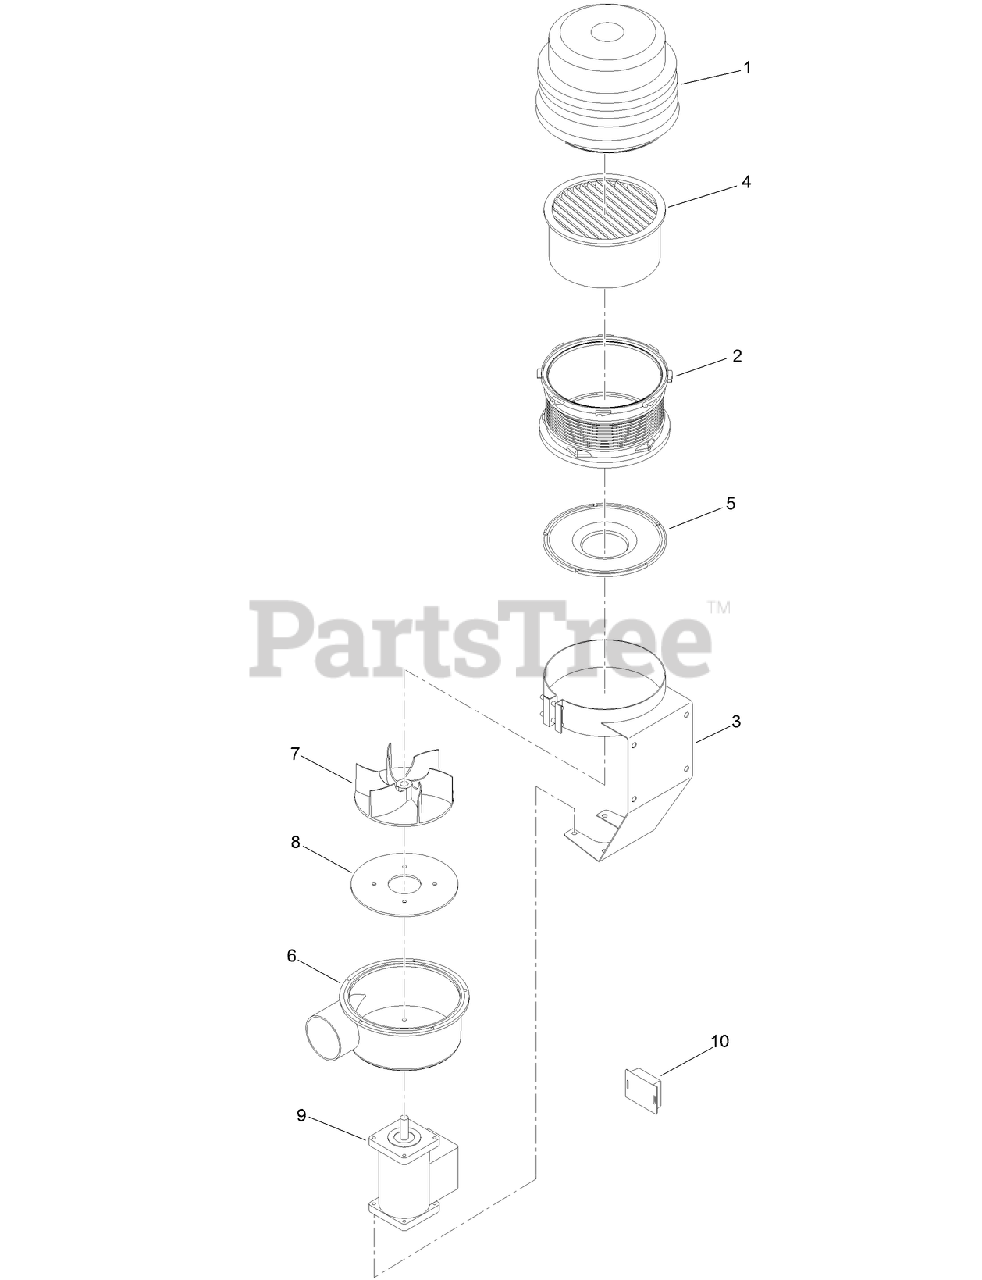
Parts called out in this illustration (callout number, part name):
1	PRECLEANER
3	BRACKET
4	ELEMENT
5	DEFLECTOR-INLET
6	HOUSING-PUMP
8	PLATE-REINFORCEMENT
10	CONTROL-PRESSURE
